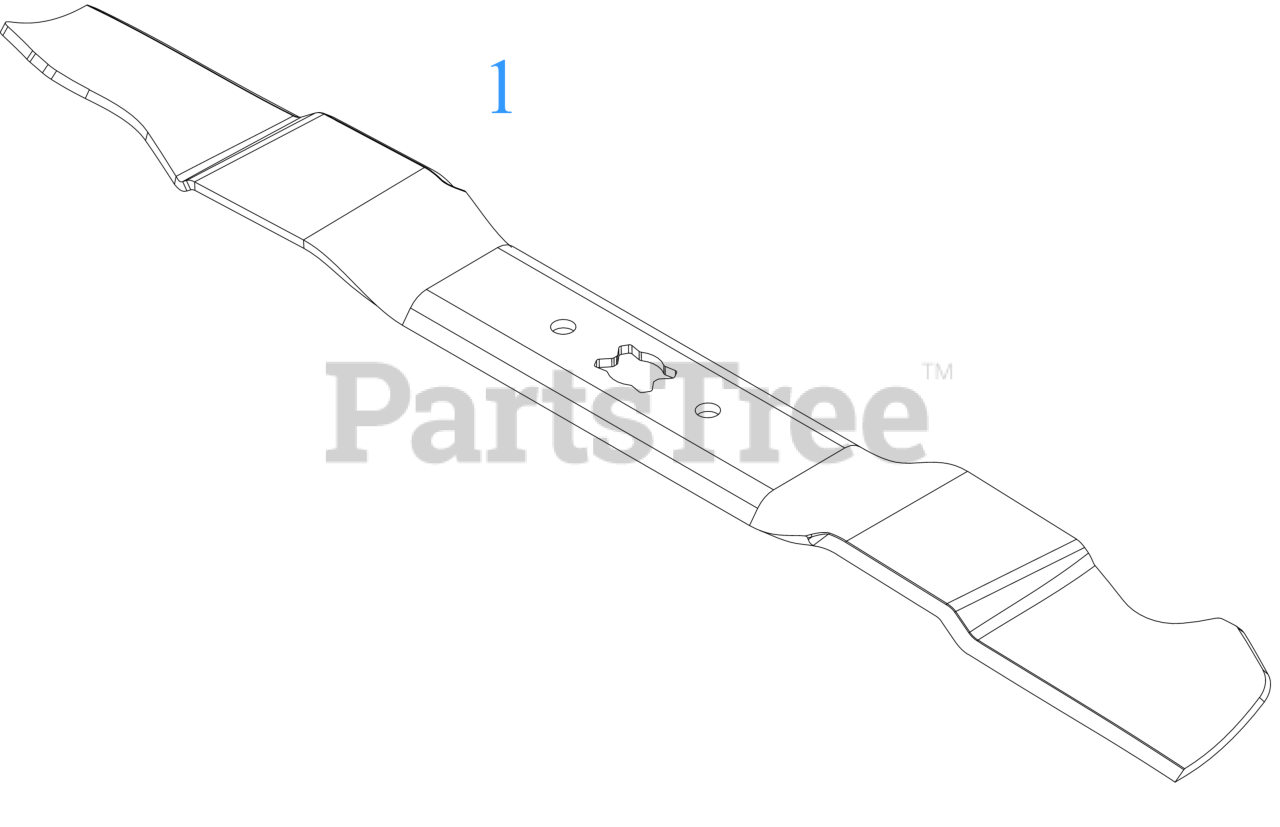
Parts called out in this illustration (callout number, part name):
1	21" BLADE (MULCH)
1	Cub Cadet 21" MULCH BLADE
1	Genuine Factory Parts 21" MULCH BLADE
1	Genuine Factory Parts 21" MULCHING BLADE (0741A)
1	21" BLADE (MULCH) (XTREME)
